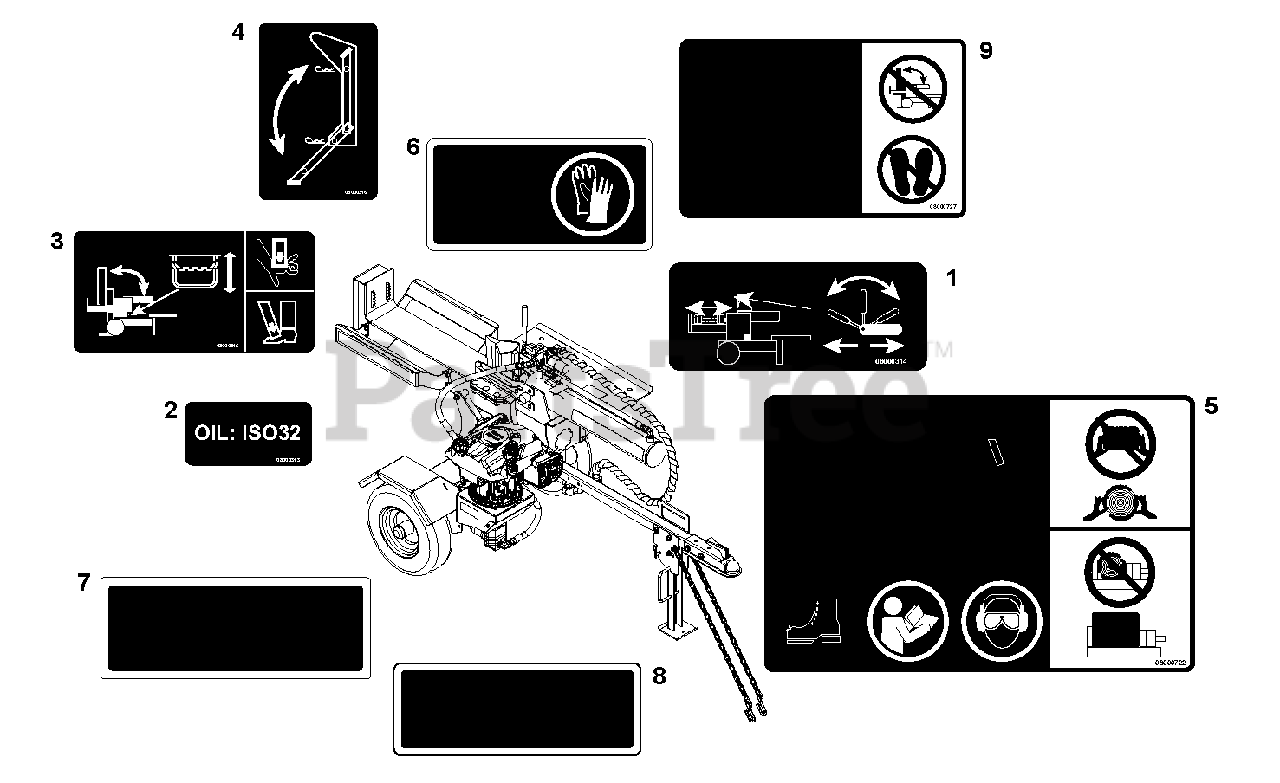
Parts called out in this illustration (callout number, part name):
1	Decal, Log Splitter - Ram Operation
2	Decal, Log Splitter - Hydraulic Oil
3	Decal, Log Splitter - Tilt Operation
4	Decal, Log Splitter - Rear Stand
5	Decal, Danger Log Splitter
6	Decal, Hydraulic Warning
7	Decal, Fuel Warning
8	Decal, Towing
9	Decal, Splitter Table
